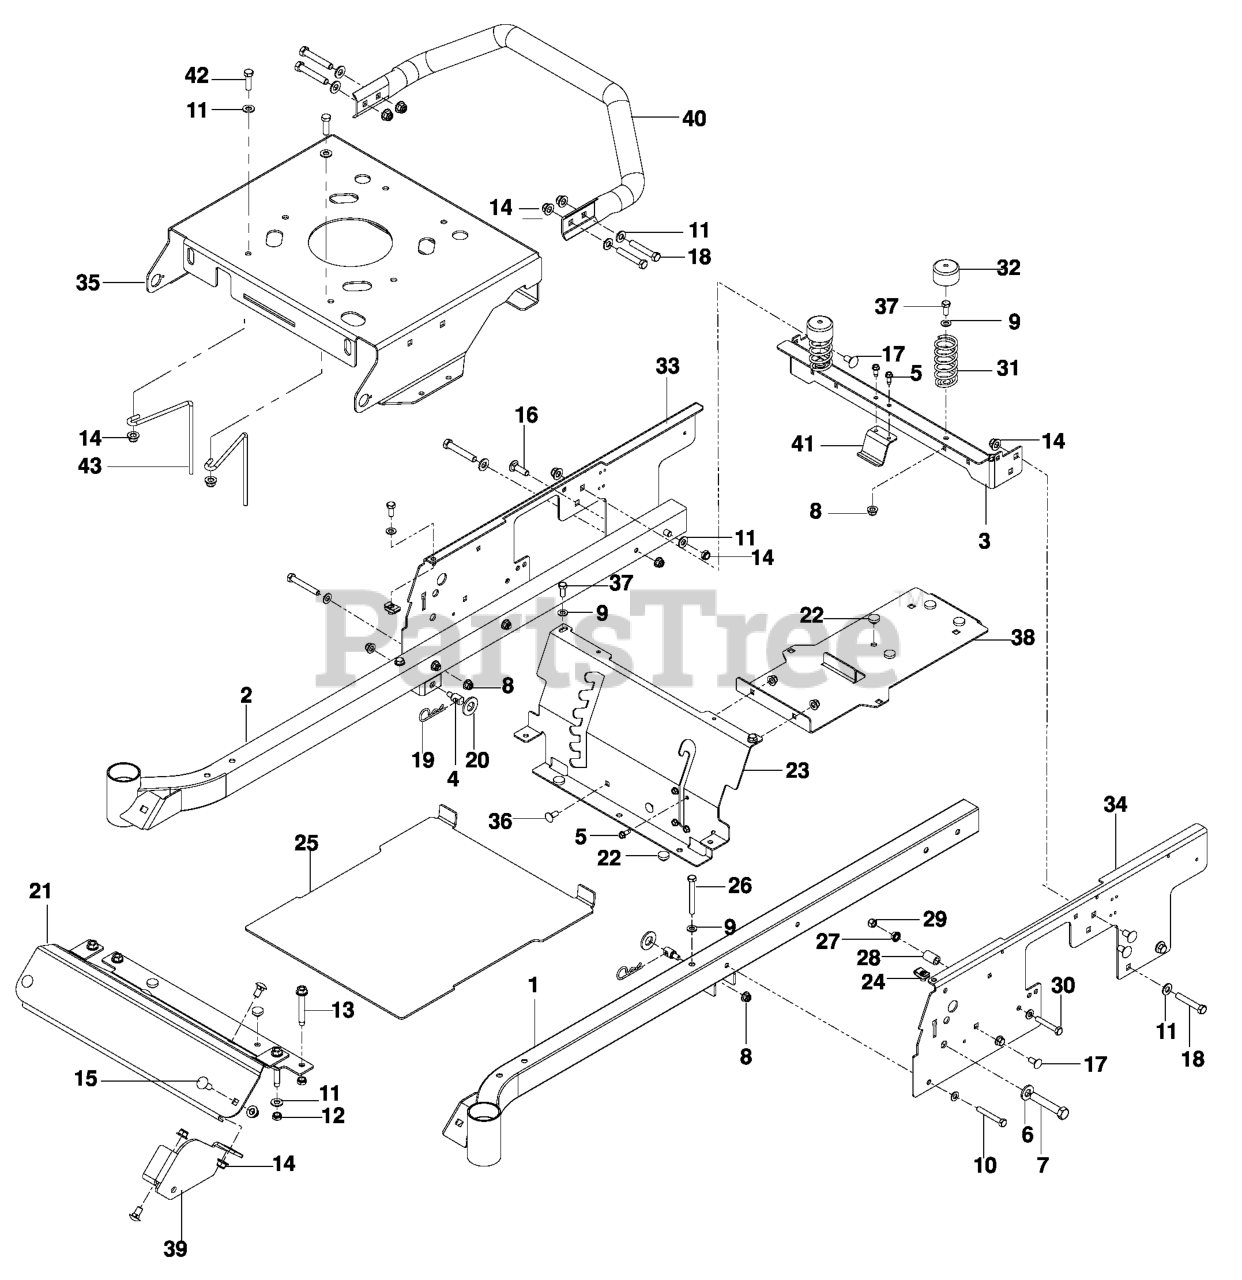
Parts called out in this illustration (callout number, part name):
1	FRAME TUBE, LH, ORG
2	FRAME TUBE, RH, ORG
3	SUPPORT, REAR SEAT, ORG
4	STUD.FASTNER.W/ANTI-ROTATE
5	SCREW 1/4 X 5/8
6	WASHER 1/2" FLAT
7	HCS 1/2C X 2 3/4
8	5/16-18 NYLOC FLANGE NUT
9	FLAT WASHER 5/16 SAE
11	WASHER 3/8 SAE FLAT
12	NUT HEX 3/8-16 NYLON, THIN
13	ENGINE BOLT, SPECIAL
14	NUT 3/8-16 HEX FLG NYLOC ZD
15	RHSNB 3/8C X 1
16	RHSNB 3/8-16 X 1-1/4
17	RHSNB 3/8-16 X 3/4 GR5 ZD
18	HCS 3/8C X 2 1/4
19	HAIRPIN #4
20	WASHER 5/8 FLAT
21	FOOT.REST.30/38.ORANGE
22	GROMMET, BUMPER
23	PANEL, SEAT SUPP, ORG
24	U-CLIP 5/16-18 NUT RETAINER
25	FOOT PLATE, NARROW, ORG
26	HCS 5/16C X 2-3/4
27	NUT 5/16C WHIZ
29	NUT 5/16 NYLOC
30	HCS 5/16-18X2
31	SEAT SPRING
32	SPRING CAP
33	PLATE, RT SIDE, ORG
34	PLATE, LT SIDE, ORG
35	PLATE, ENGINE, ORG
36	BOLT 5/16C X 3/4" CARRIAGE
37	HCS 5/16C X 3/4
38	SUPPORT, TANK/BATT, BLK
39	BRACKET, FRONT DECK, BLK
40	IMPACT BAR, ORG
41	HOLDING DEVICE, FUEL TANK, BLK
42	HCS 3/8C X 1 1/4 GR5
43	BELT GUIDE
